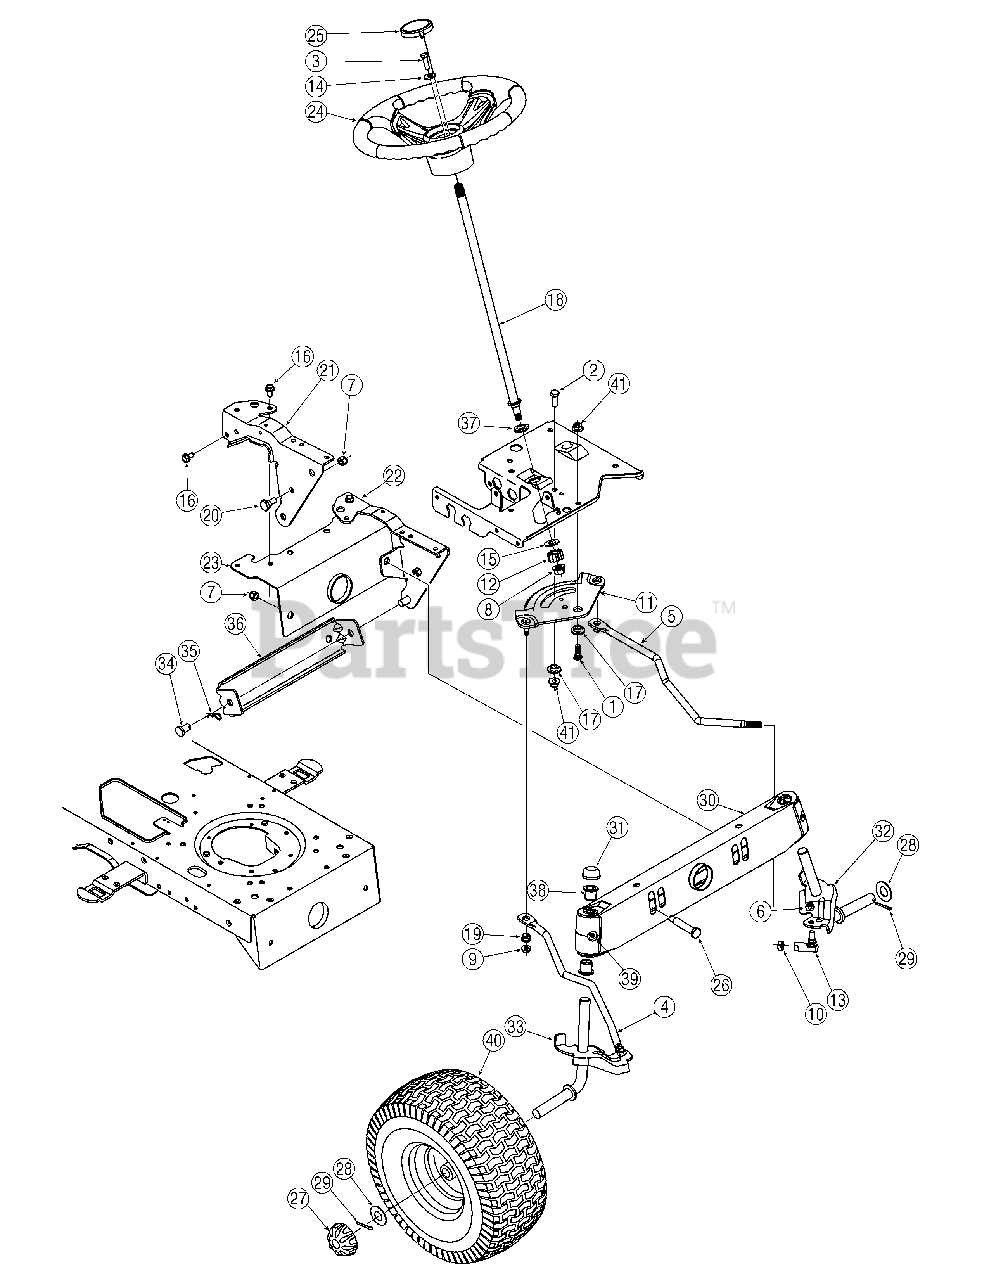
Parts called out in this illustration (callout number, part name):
1	Hex Screw, 3/8-16, 1.00, Gr5
2	Hex Screw, 3/8-16, 1.00, Gr5
3	Hex Screw, 5/16-18, 1.00, Gr5
4	Link, Drag, RH
5	Link, Drag, LH
6	Nut, Hex Lock, 3/8-24
7	Nut, Flange Lock, 3/8-16, Grf
8	Nut, Flange Lock, 7/16-20
9	Nut, Flange Lock, 5/16-18, Gr5
10	Nut, Jam, 7/16-20, Gr2
11	Gear, Steering, 11/90 Ratio
12	Gear, Pinion, Steering
13	Ball Joint, 7/16-20, Lock
14	Washer, Flat, .406 x .875 x .105
15	Washer, Flat, .51 x 1.12 x .06
16	Screw, 5/16-18, 0.750
17	Spacer, Shoulder, .38 x 1.00 x .31
18	Shaft, Steering, .625 OD x 24.25
19	Plastic Bushing .380 ID
20	Screw, Shoulder, .498 x .340
24	Steering Wheel
25	Steering Wheel Cap
26	Shoulder Screw, .5 x 2.2, 3/8-16
27	Deluxe Hub Cap
28	Flat Washer, .78 x 1.589 x .06
29	Cotter Pin, 5/32 x 1.25
31	Push Cap
32	LH Axle Assembly, .750
33	RH Axle Assembly, .750
34	Pin, Clevis, .50 x .78
35	Cotter Pin, Internal, .080 x 1.5625
37	Hex Flange Bearing
38	Flange Bearing, .760 x .941 x 1.0
39	Pivot Bar Endcap
41	Flange Lock Nut, 3/8-16
